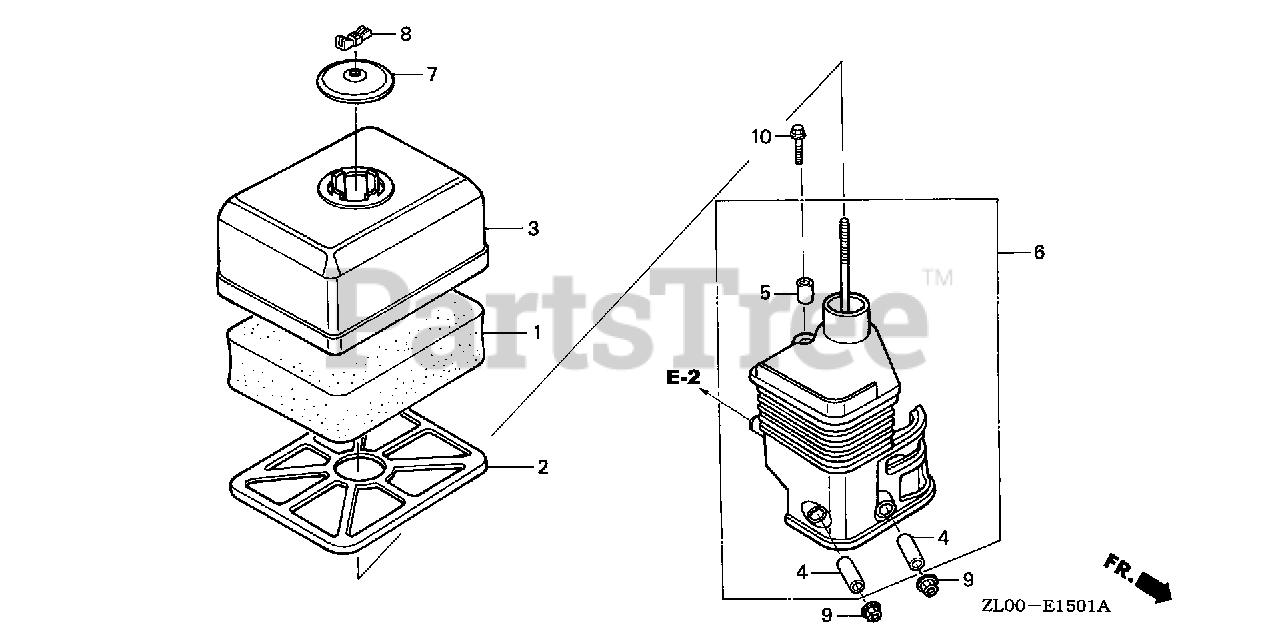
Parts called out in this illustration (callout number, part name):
1	ELEMENT, AIR CLEANER (SEMI-DRY)
2	GRID, AIR CLEANER (SEMI-DRY)
3	COVER, AIR CLEANER (SEMI-DRY)
4	COLLAR, AIR CLEANER
5	COLLAR B, AIR CLEANER
6	ELBOW, AIR CLEANER
7	CAP, CLEANER
8	NUT, TOOL BOX SETTING
9	NUT, FLANGE (6MM)
10	BOLT, FLANGE (6X20)
